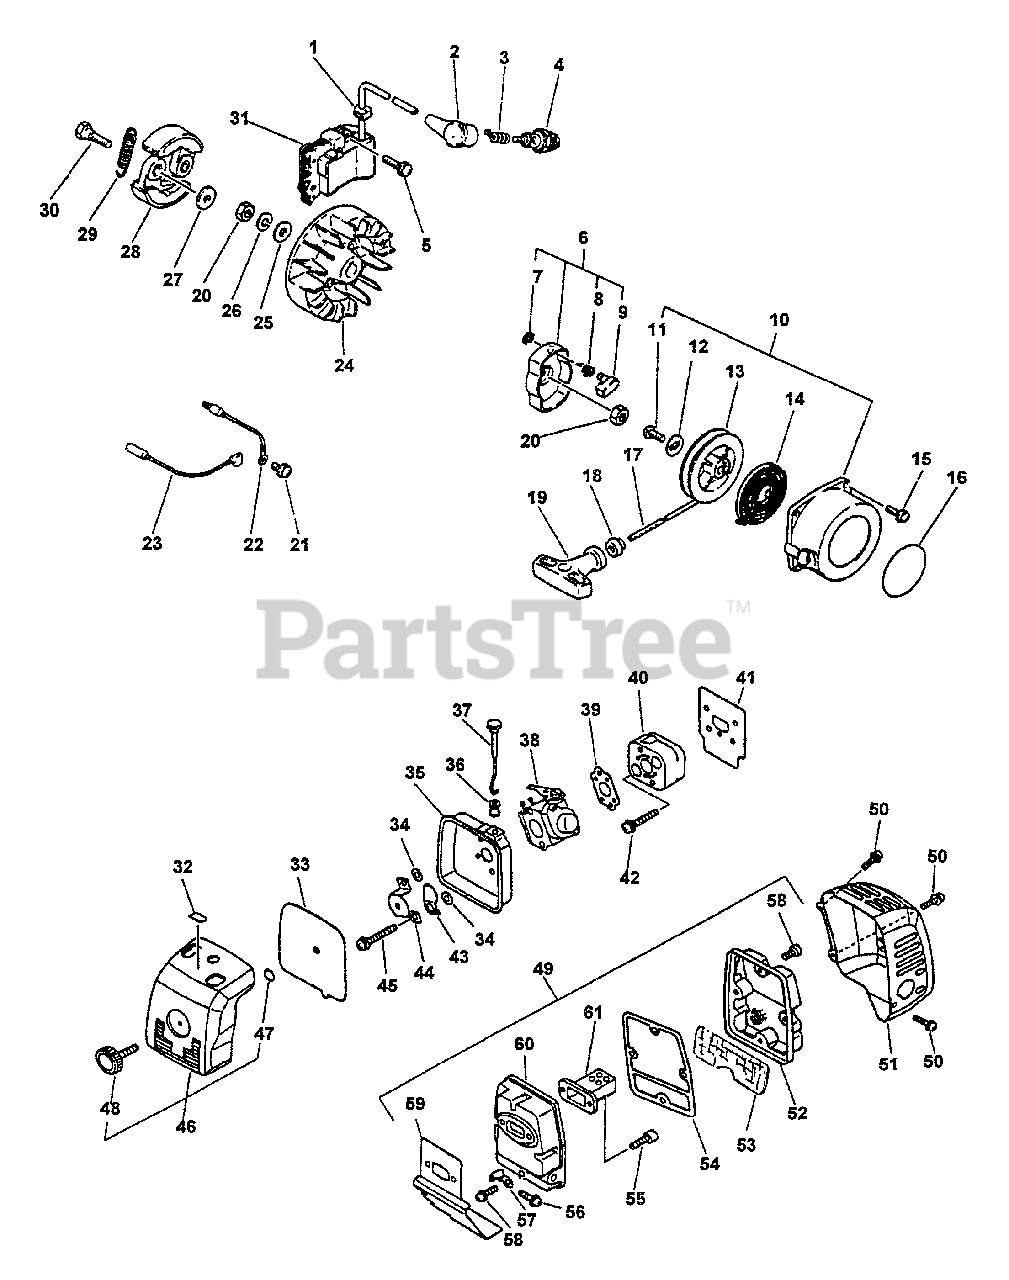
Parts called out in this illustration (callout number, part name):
2	CAP, SPARK PLUG
3	TERMINAL, SPARK PLUG CAP
4	SPARK PLUG -- BPM-7A
5	SCREW - 5X20
6	STARTER PAWL ASSY
7	RING, RETAINING - 4
8	SPRING, RETURN
9	PAWL, STARTER
10	STARTER ASSY - GRAY
12	WASHER
13	REEL, ROPE
14	SPRING, REWIND
15	SCREW - 4X14
16	LABEL - ECHO
17	ROPE, STARTER - 3.5X850
18	GUIDE, ROPE
19	GRIP, STARTER
21	SCREW - 5X10
22	LEAD - GROUND
23	LEAD - GROUND
24	FLYWHEEL
25	WASHER - 8
26	LOCKWASHER - 8
27	WASHER - 6
28	SHOE, CLUTCH
29	SPRING, CLUTCH
30	BOLT, CLUTCH
31	COIL, IGNITION
32	LABEL - CHOKE
33	FILTER, AIR - HEAVY DUTY
34	WASHER - 5
35	CASE, AIR FILTER
37	ROD, CHOKE
38	CARBURETOR C1U-K20B
39	GASKET, INTAKE
40	INSULATOR, INTAKE
41	GASKET, INTAKE
42	SCREW - 5X25
43	SHUTTER, CHOKE
44	PLATE, PREVENT
45	SCREW - 5X50
46	AIR FILTER COVER ASSY
47	O-RING - 3
48	THUMBSCREW
49	MUFFLER ASSY
50	SCREW - 4X8
51	COVER, MUFFLER
52	LID, MUFFLER
53	SCREEN, SPARK ARRESTOR
54	GASKET, EXHAUST
55	SCREW - 5X18
56	SCREW - 5X10
57	BRACKET, MUFFLER
58	SCREW - 5X14
59	GASKET, EXHAUST
61	BAFFLE, MUFFLER
